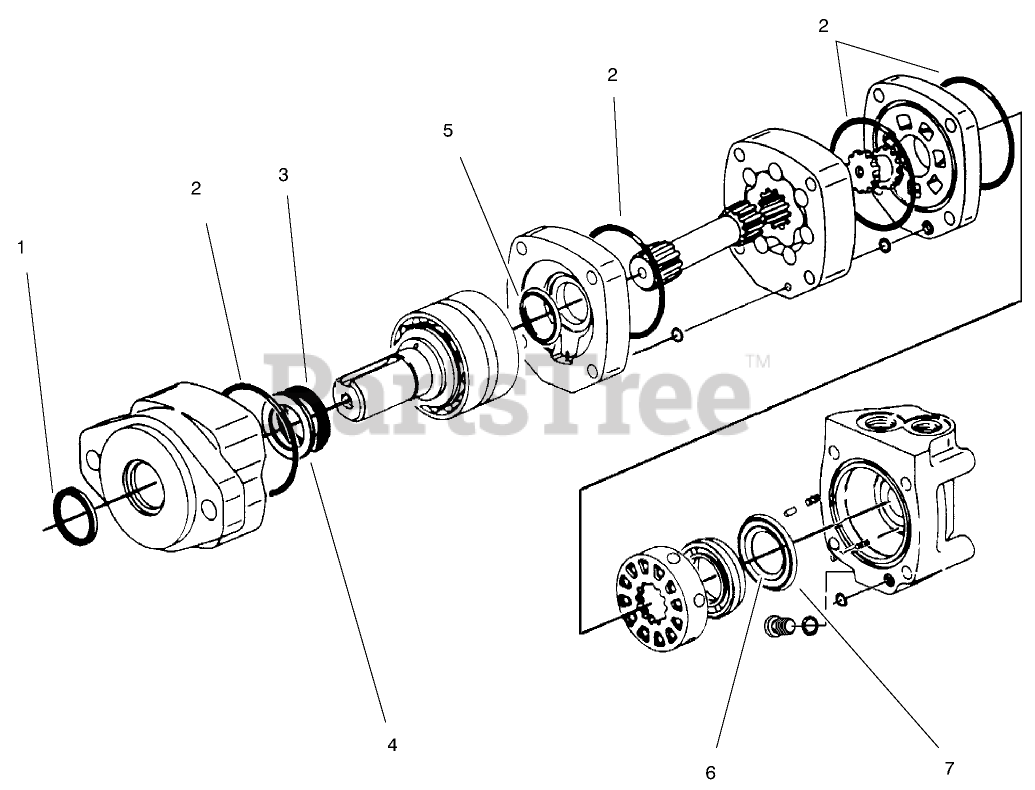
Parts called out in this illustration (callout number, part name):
2	Seal-O-Ring
4	Back-Up Washer
7	Seal-Outer
